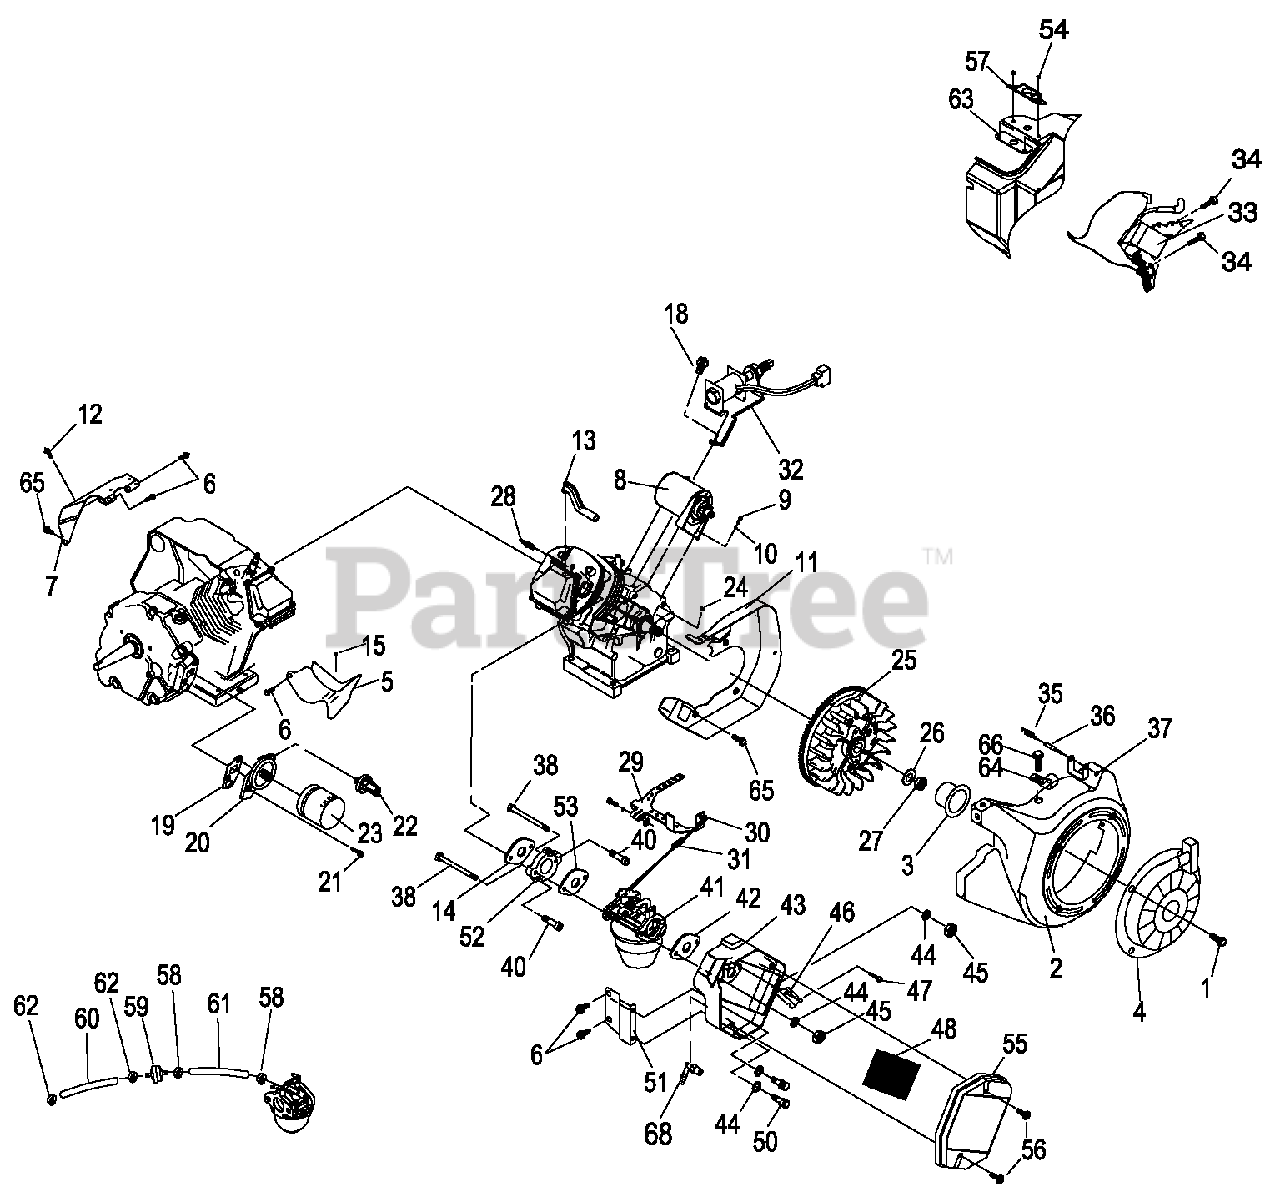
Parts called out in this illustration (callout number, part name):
1	SCREW HHTT M6-1.0 X 8 ZYC
2	ASSEMBLY, BLOWER HOUSING
3	PULLEY STARTER LARGE FRAME
4	RECOIL STARTER LARGE FRAME
5	WRAPPER, BOTTOM 12 HP HS
6	SCREW HHTT M6-1.0 X 10 YELLOW CHROME
7	WRAPPER, TOP REGULAR STEEL
8	ASSEMBLY, STARTER 46
9	SCREW SHC M8-1.25 X 40
10	WASHER, LOCK M8-5/16
11	BACKPLATE, W/ ELECTRIC START
12	SCREW, HHTT 5/16 - 18 X 1/2" CLEAR
13	HOSE, BREATHER GH410 ENGINES
14	GASKET, INTAKE ADAPTER
15	GROMMET 9/16 X 1/16 X 7/16
18	SCREW HHTT M8-1.2 X 16 YC
19	GASKET,OIL FILTER ADAPTER
20	ADAPTER OIL FILTER W/TAPD HOLES
21	SCREW, SHC M8-1.25 X 30 G12.9
22	SWITCH, HOBBS OIL PRESSURE 5PSI
23	FILTER, OIL BLACK 75 LONG, LOGO
24	KEY, WOODRFF 4 X 19D
25	FLYWHEEL, WITH RING GEAR 27 DEGREE
26	WASHER,BELV-20 X 2.2
27	NUT HEX M20-1.5 G8 YLW CHROME- FLYWHEEL
28	SPARKPLUG, CHAMPION RC14YC
29	ASSEMBLY,GOVERNOR LEVER 12HP
30	ROD, GOVERNOR CONTROL
31	SPRING, ANTI-LASH
32	IDLE COIL ASY,GOV LF
33	ASSEMBLY, IGNITION ADV NO DIODE GH410
34	SCREW HHFC M6-1.0 X 25
35	SPRING GOVERNOR 320/360/410
36	BOLT, GOVERNOR ADJUSTMENT M5
37	NUT, HEX LOCK M5-0.8 NYLON INSERT ZINC
38	BOLT, CARBURETOR MOUNTING
40	FLANGE HEAD SCREW, SHC M6-1.0 X 20 G8.8ZP
41	CARBURETOR ASSEMBLY, 410HS
42	GASKET, AIR CLEANER
43	BASE, AIR CLEANER 410 HI FLOW XP PORT
44	WASHER, FLAT M6
45	NUT, HEX LOCK M6-1.0 NYLON INSERT
46	PLATE, SPITBACK
47	SCREW HWHTF 8-18 X 0.5 HI-LOW
48	ELEMENT, AIR FILTER
50	SCREW, HHC M6-1.0 X 16 W/ LOCK WASHER
51	BRACKET, AIR CLEANER
52	ADAPTER, "K"
53	GASKET, CARBURETOR/MANIFOLD
54	RIVET, 1/8"
55	COVER, AIR CLEANER 13GN
56	BOLT, AIR CLEANER COVER
57	BRACKET, CHOKE CABLE
58	CLAMP, HOSE
59	FILTER, FUEL
60	HOSE, FUEL, 105MM LONG
61	HOSE,1/4" SAE30R7 SETIFLEX 13"
62	CLAMP HOSE BAND .50
63	BACK PLATE
65	SCREW HHFC M6-1.0 X 12
66	SCREW, HHTT M6-1.0 X 10 ZYC
67	ENGINE HARNESS XP6.5 AND XP8.0
68	BARBED ELBOW
